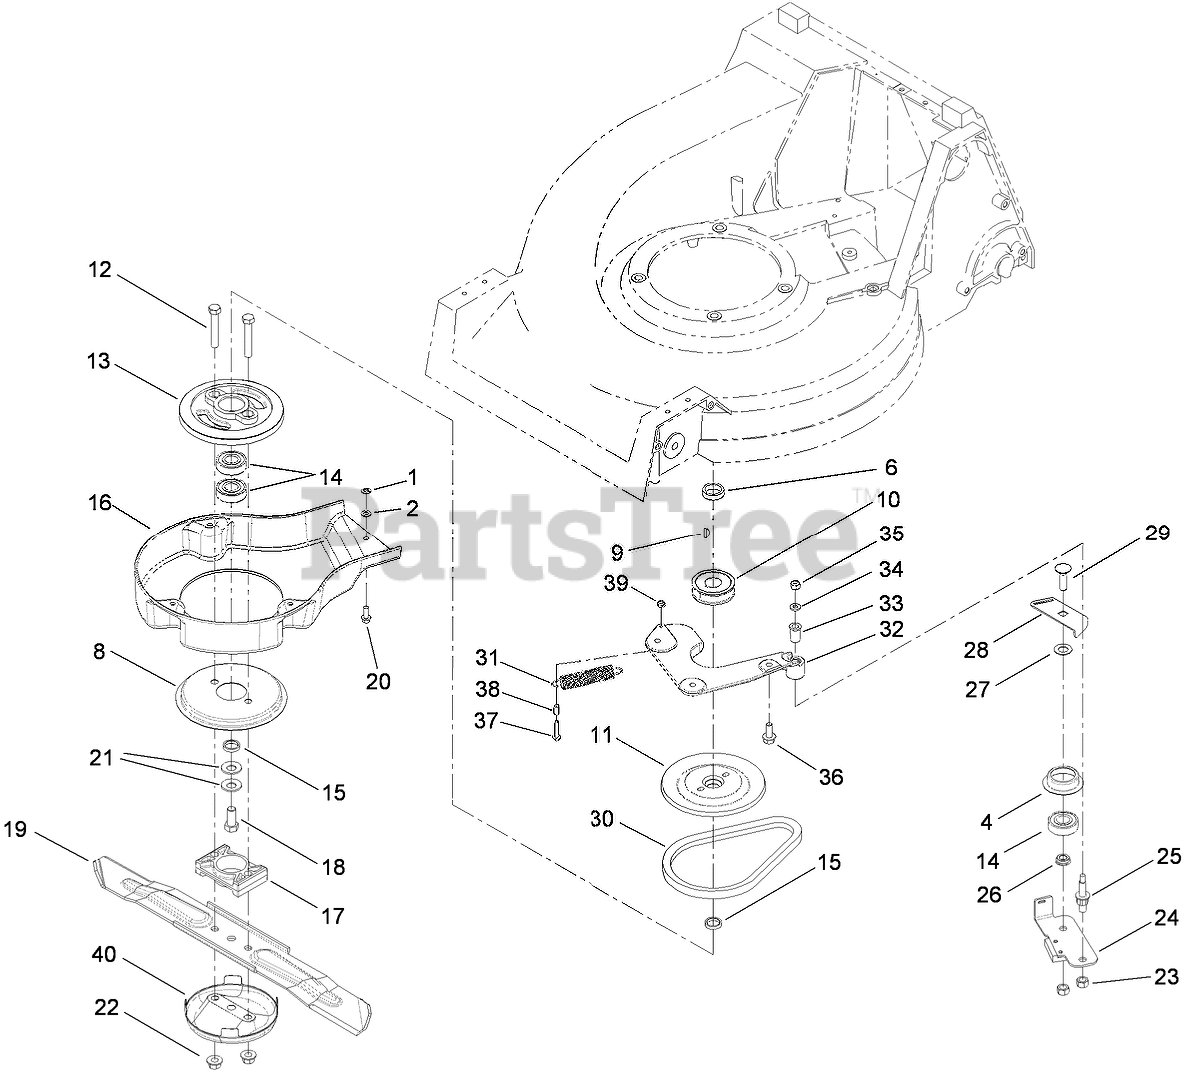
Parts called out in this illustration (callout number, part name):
1	NUT-RETAINER
2	WASHER-FLAT
4	RETAINER-BELT
6	SPACER-PULLEY
8	DISC
9	KEY-WOODRUFF
10	PULLEY-DRIVER
11	PULLEY-DRIVER, UPPER
12	SCREW-HH
13	DRUM
14	BEARING-BALL
15	SPACER-PLATE, BBC
16	SHIELD-BBC
17	SPACER-BLADE
18	SCREW-HH
19	BLADE-21 INCH
20	SCREW-HWH
21	WASHER-SPRING
22	NUT-LOCK
24	BRAKE ARM ASM
25	BOLT-SHOULDER
26	SPACER-BEARING
27	WASHER-PLAIN
28	PLATE-GUIDE
29	BOLT-CARR
30	BELT
31	SPRING-EXTENSION
32	PLATE-MOUNTING, BBC
33	BUSHING
34	WASHER-FLAT
35	NUT-LOCK, NI
36	SCREW-HHF
37	SCREW-TAP
38	SPACER-BBC
39	NUT-LOCK, NI
40	CUP-SCALP, ANTI
